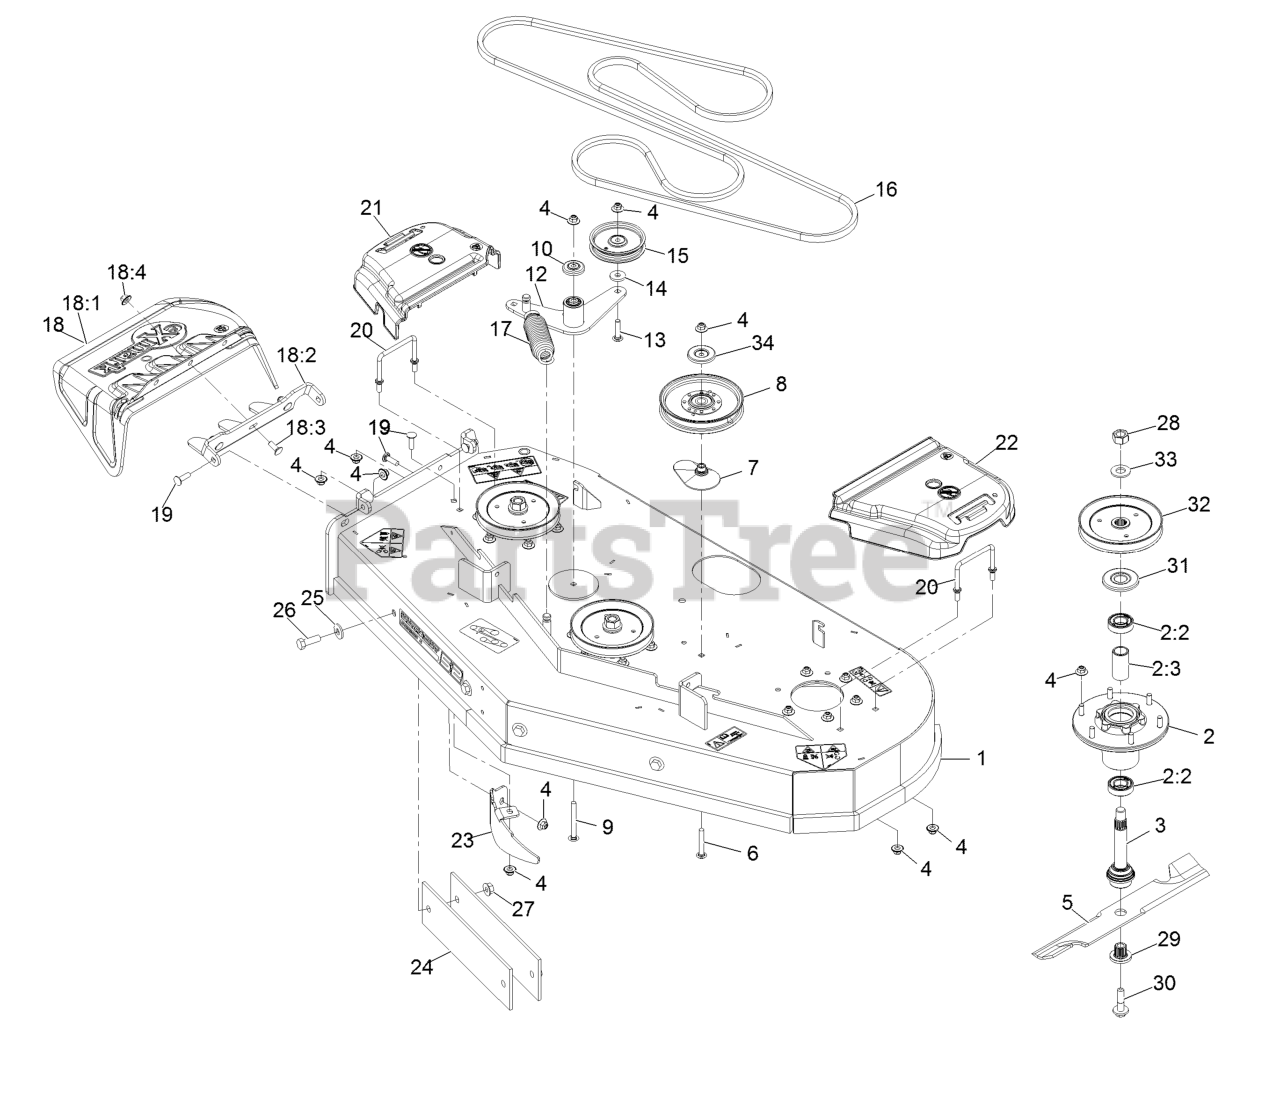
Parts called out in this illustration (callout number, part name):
1	Deck ASM-524
2	ASM-Cutter Hsg With Bearings
2:2	Bearing-Ball
2:3	Spacer-Bearing
3	ASM-Spindle And Seal
4	Nut-Nyloc 3/8-16 Flg
5	Blade, Mulching
5	Blade, Solid
5	Blade-Extreme 2, 18.00"
5	Blade-Notched
5	Blade, Low Lift
6	Screw-CARR
7	Spacer-Pulley
8	Idler-Pulley
9	Bolt-Carriage 3/8-16 X 3 1/2
10	Guard-Top
12	Idler Arm ASM W/Bearings
13	Bolt-Carriage 3/8-16 X 1 3/4
15	Pulley-Idler
16	Belt-V
17	Spring-Extension
18	ASM,Discharge Chute
18:1	Chute, Discharge
18:2	Bracket,Discharge Chute
18:3	Bolt-Carriage 3/8-16 X 1
18:4	Nut-Nyloc 3/8-16 Flg
19	Bolt-Carriage 3/8-16 X 1 1/4
20	Wireform-Cover
21	Cover-Belt, RH
22	Cover-Belt, LH
23	Baffle-Dogleg, Lz-Vt52
24	Bar,Weight
25	Washer-Spring Disc 1/2
26	Screw-HH 1/2-13 X 1 1/2
27	Nut-Whizlock 1/2-13
28	Nut-Hex
29	Bushing, Splined
30	Screw-Sems 1/2-20 X 2.19
31	Guard,Bearing Top .989
32	Sheave,Blade Drive 6.50
33	Washer-Spring Disc 3/4
34	Shield-Dust
